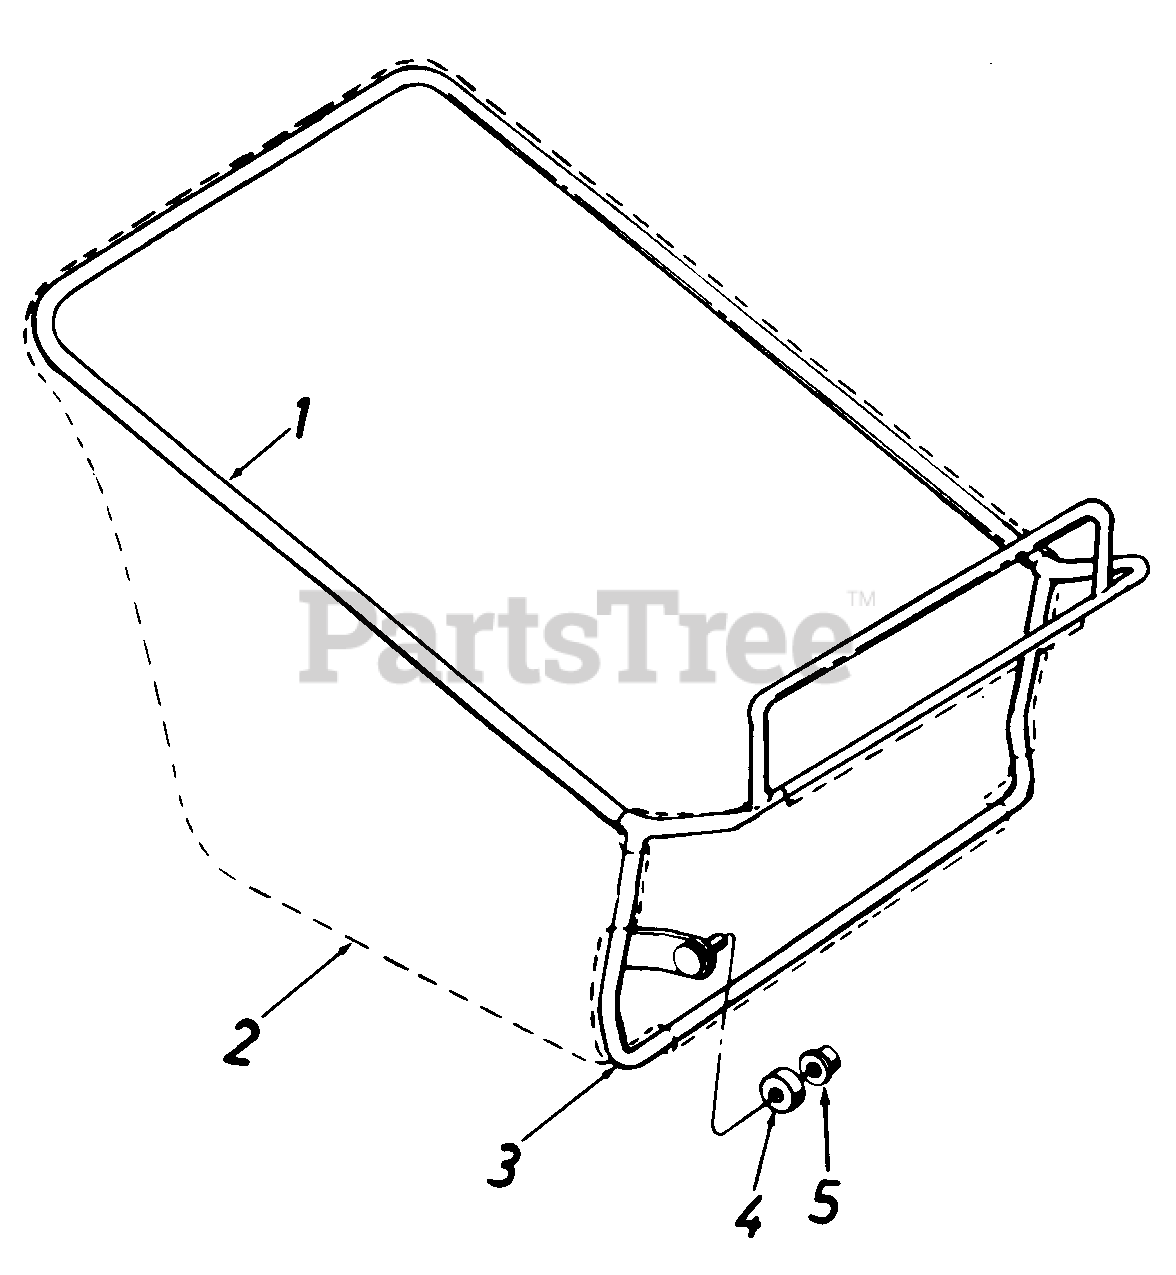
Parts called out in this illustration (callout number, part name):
1	Upper Frame
2	Grass Bag
5	Push Cap
